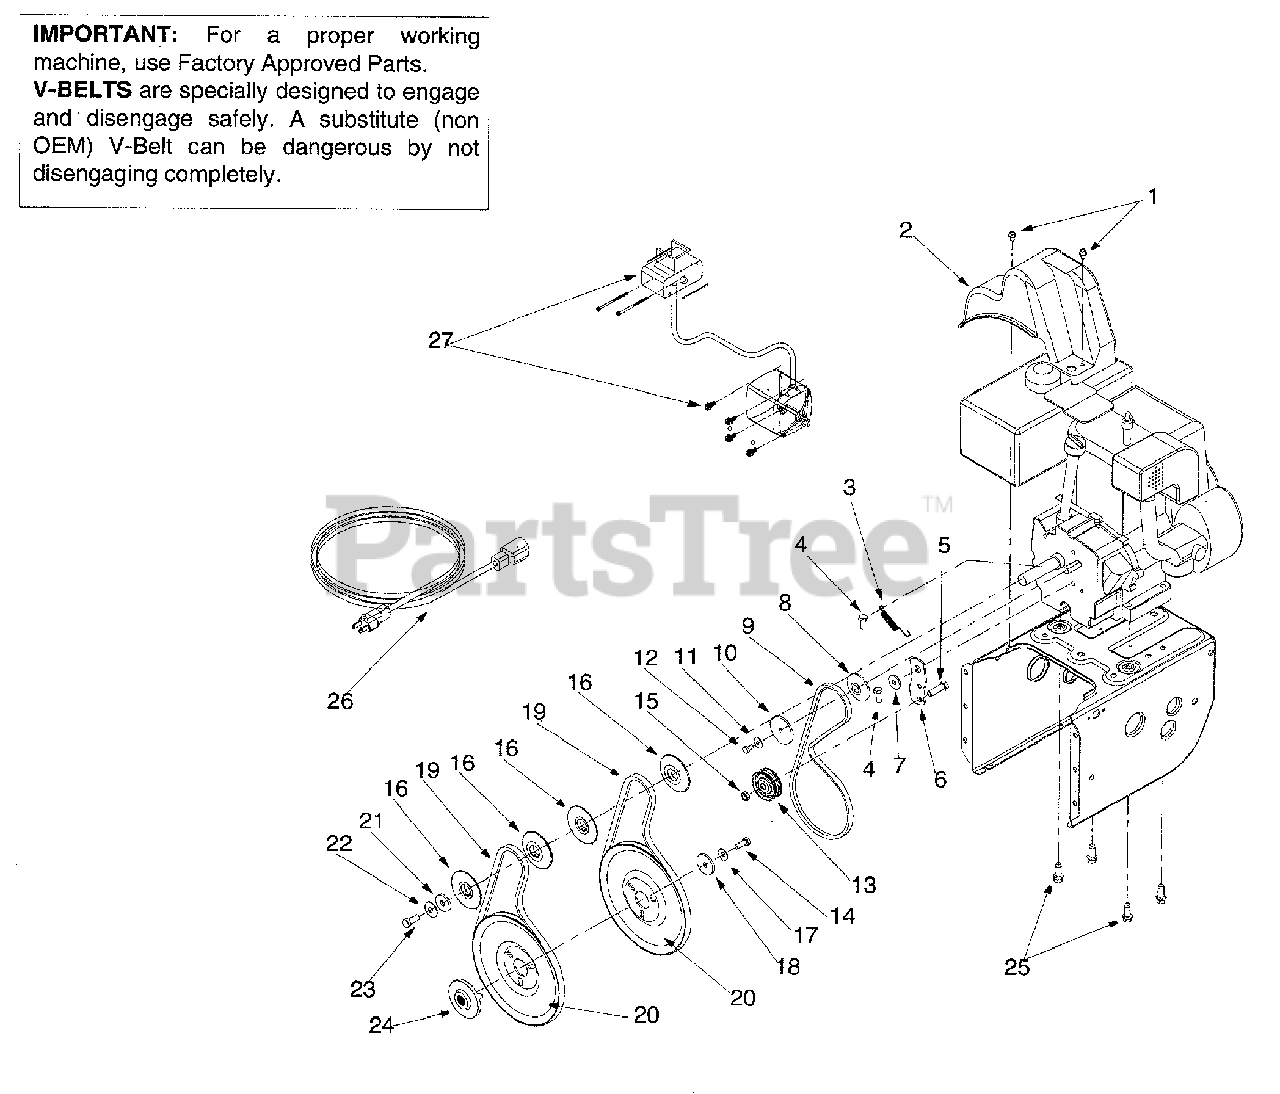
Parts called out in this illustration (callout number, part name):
1	Hex Washer Screw 1/4-20 x .50
2	Belt Cover
3	Extension Spring
4	Hex Screw 5/16-24 x .75
5	Hex Cap Screw 3/8-16 x 1.25
8	Pulley Half
9	V-Belt
10	Pulley Half
11	Bell Washer
12	Hex Cap Screw 1/4-28 x .50
13	Flat Idler
14	Lock Hex Cap Screw 5/16-24
15	Lock Jam Nut 3/8-16
16	Pulley Half
17	Bell Washer
18	Flat Washer
19	Belt
20	Auger Pulley
21	Flat Washer 3/8 x 1.25 OD
22	Bell Washer
23	Hex Cap Screw 3/8-24
24	Adapter Pulley
25	Hex Screw 3/8-16 x 1.0
26	Extension Cord
27	Electric Start
